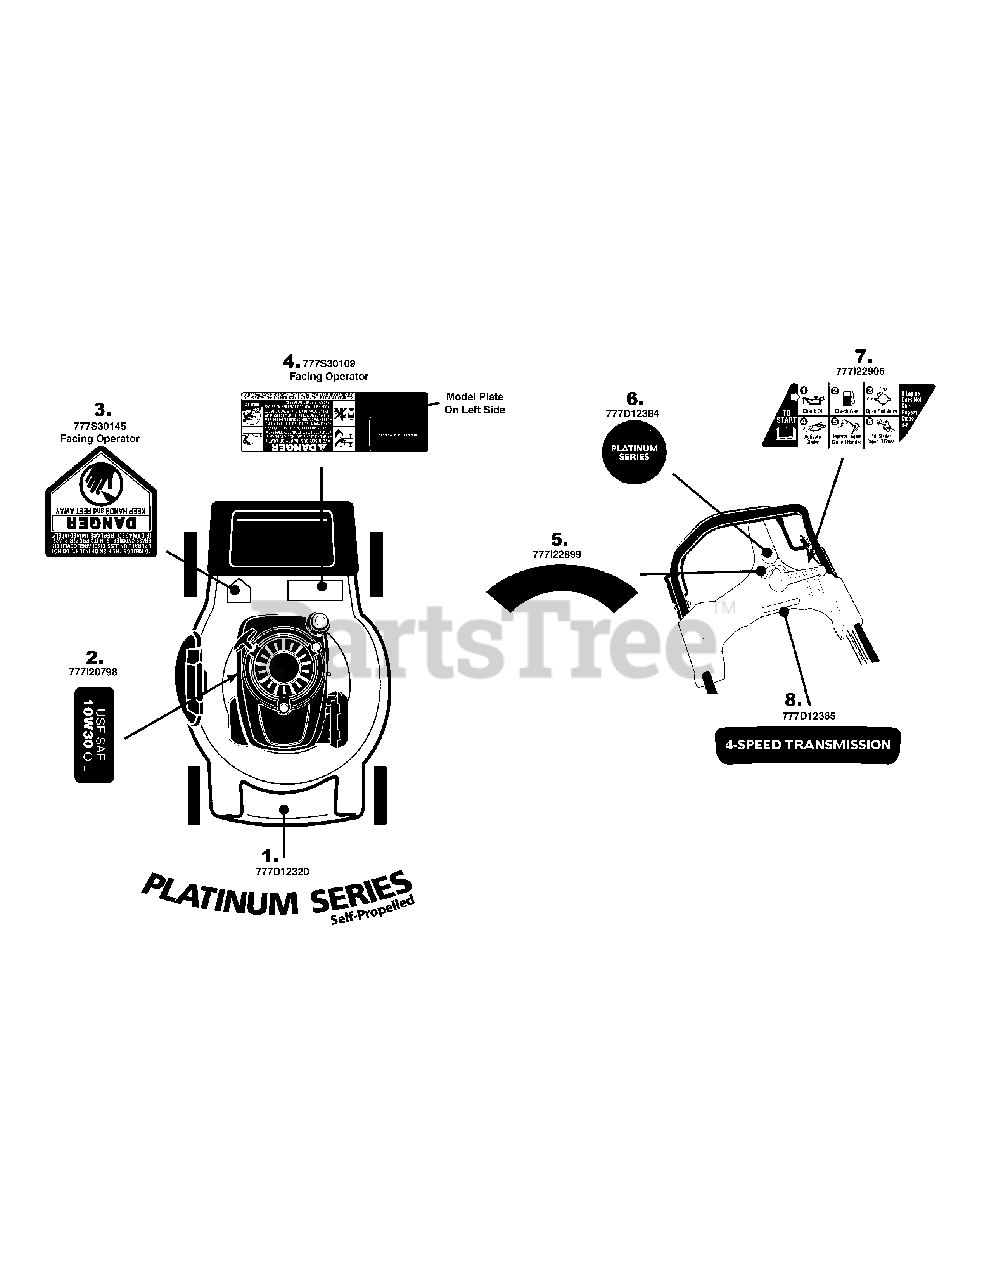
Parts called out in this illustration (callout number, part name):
1	LABEL-MOWER DECK PLATINUM SERIES
2	LABEL-SHROUD
3	LABEL
4	LABEL-MOWER DANGER
5	LABEL-MOWER XP HANDLE SELECT
6	LABEL-MOWER 4 SPD HANDLE PLATINUM
7	LABEL-MOWER HANDLE HONDA
8	LABEL-MOWER HANDLE 4SPD PLATINUM
